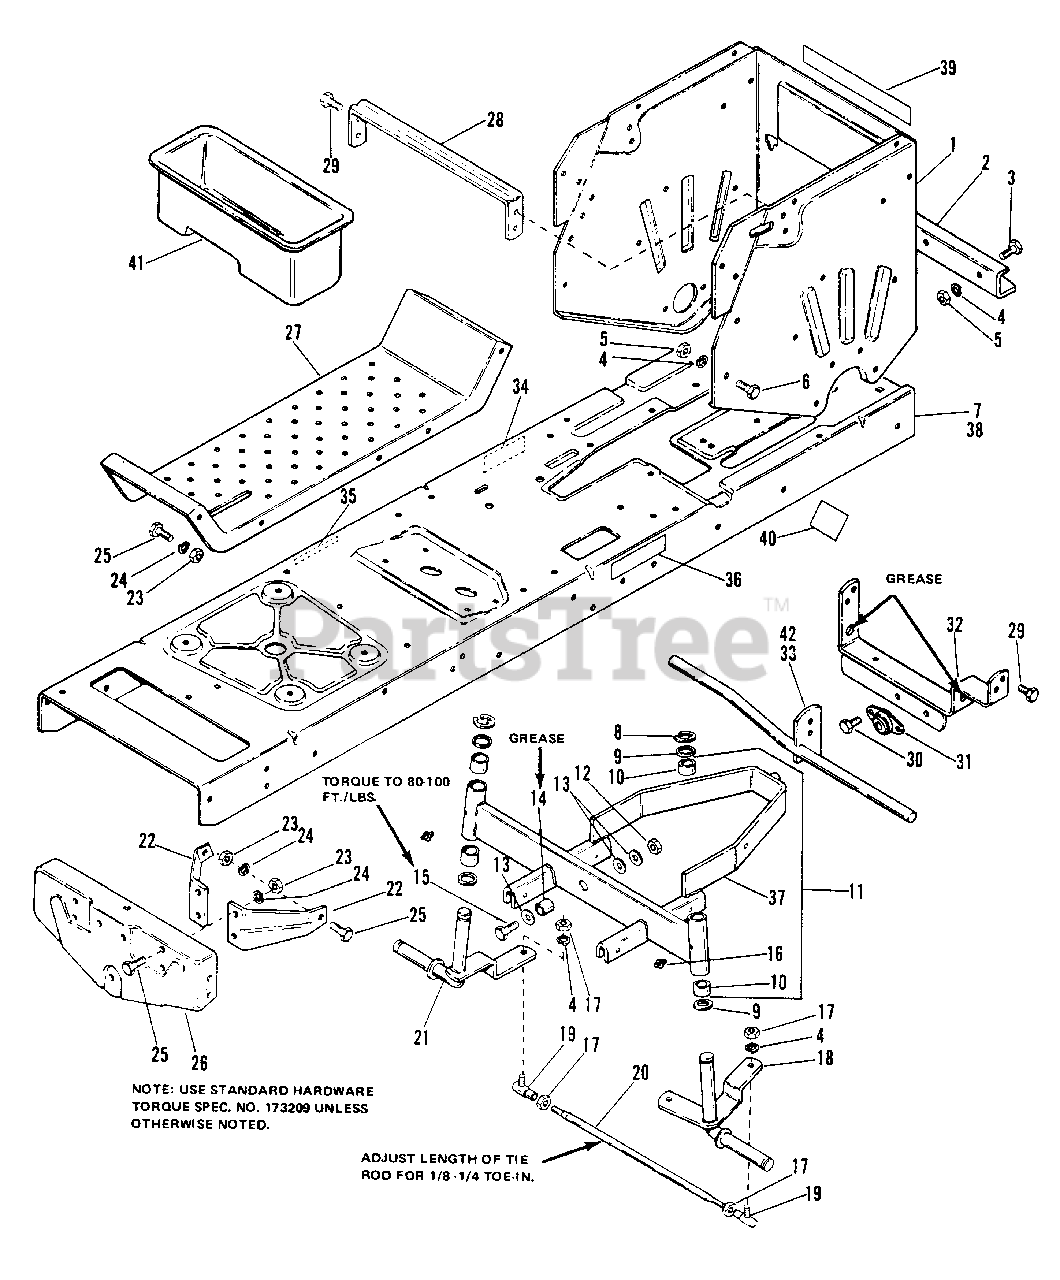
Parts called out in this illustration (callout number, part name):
1	SUPPORT, Rear frame
2	DRAW BAR
3	CAPSCREW, 3/8-16 x 1
4	LOCKWASHER, 3/8
5	NUT, Hex, 3/8
6	CAPSCREW, 3/8-16 x 3/4
7	FRAME SUPPORT ASSEMBLY (4008)
8	RING, Retaining
11	FRONT AXLE ASSEMBLY
12	LOCKNUT, Hex, 1/2-13
13	WASHER, Plain
15	CAPSCREW, 1/2-13 x 1-1/2
16	FITTING, Grease
17	NUT, 3/8-24
18	SPINDLE, L.H.
19	JOINT, Ball
21	SPINDLE, R.H.
22	BRACE, Front Axle
23	NUT, Hex, 5/16-18
24	LOCKWASHER, 5/16
25	CAPSCREW, 5/16-18 x 3/4
26	SUPPORT, Front Axle
27	FOOT REST
28	BRACE, Seat
29	SCREW, Taptite, 5/16-18 x 5/8
30	SCREW, Taptite, Washer head, 3/8-16 x 1/2
31	BEARING ASSEMBLY, Side Flange
32	AXLE SUPPORT ASSEMBLY
33	BRAKE LEVER ASSEMBLY (4008, 4108)
34	DECAL, Parking Brake
35	DECAL, Clutch, Brake
36	DECAL, PTO & Mower Lift (4108) (4208)
37	AXLE ASSEMBLY, Front
38	FRAME, (4108 & 4208)
39	DECAL, Transaxle (4208)
40	DECAL, Parking Brake (4208)
41	TRAY,Tool, (4208)
42	BRAKE LEVER ASSY., (4208)
